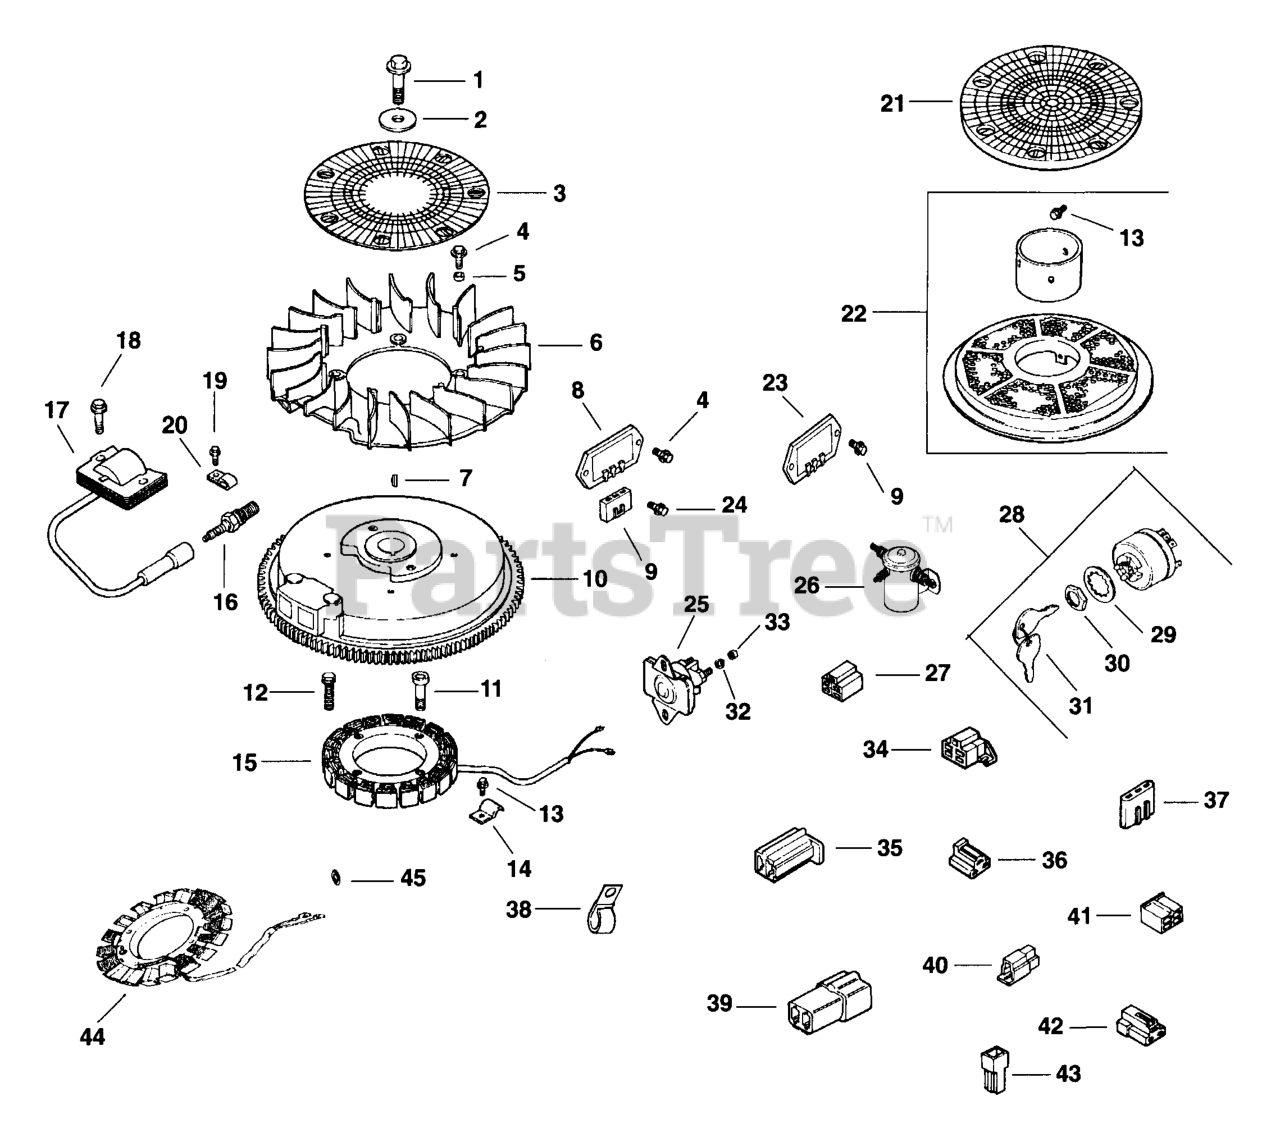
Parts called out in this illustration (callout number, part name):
1	Screw, Hex. Flange M10x1.5x45.8
2	Washer, Plain 3/8"
3	Screen, Grass
4	Screw, Hex. Flange M6x1.0x16
5	Spacer, Fan
6	Fan, Flywheel
10	Flywheel
12	Screw, Sems Hex. Cap 10-32x9/16"
13	Screw, Hex. Flange M5x0.8x10
16	Spark Plug
17	Module, Ignition
18	Screw, Hex. Flange M5x0.8x20
20	Clip, Kill Lead
